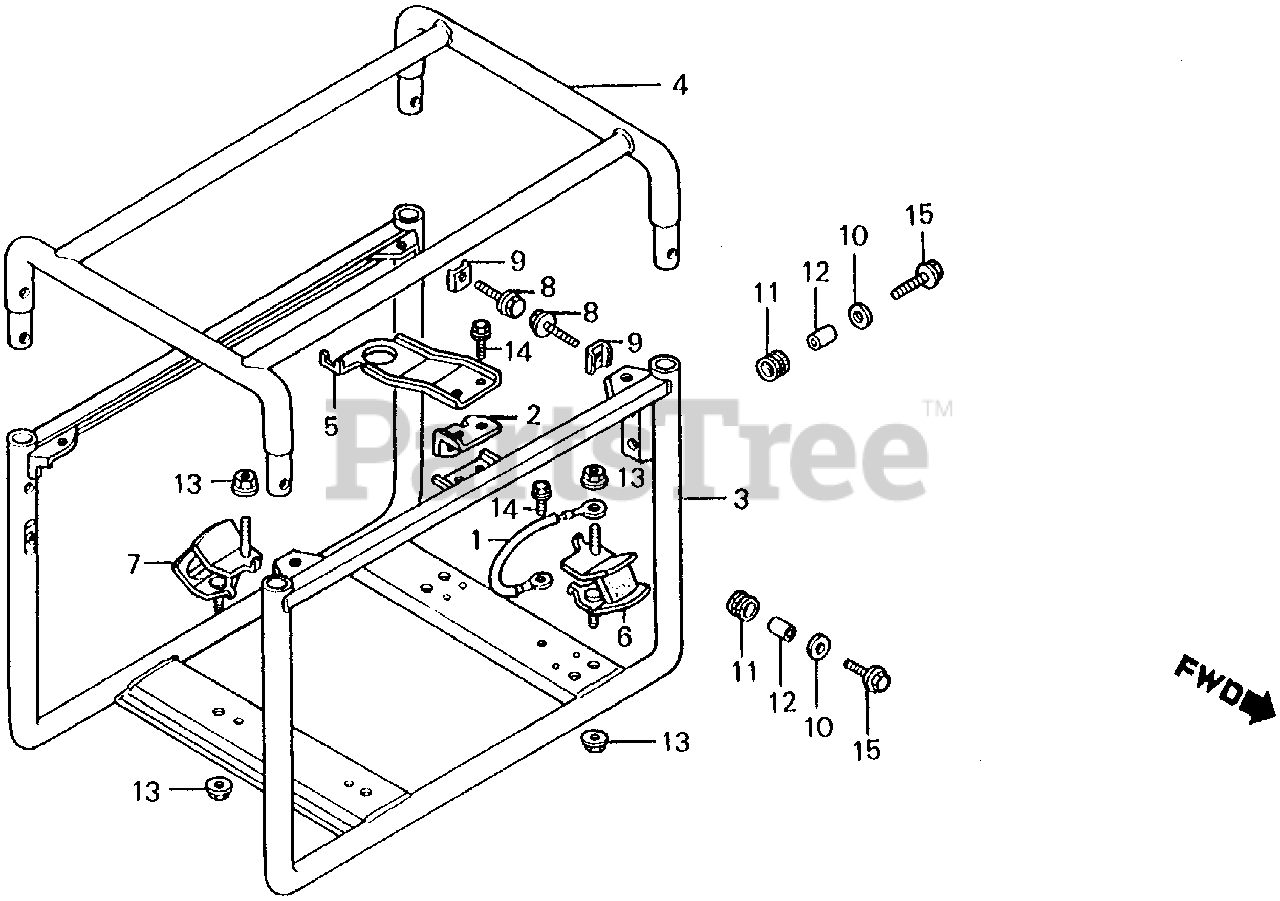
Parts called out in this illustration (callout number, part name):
1	CABLE, GROUND
2	BRACKET, CONTROL BOX MOUNTING
3	FRAME (LOWER)
4	FRAME (UPPER)
5	STAY, BUMP STOP
6	RUBBER, FR. (LOWER)
7	RUBBER, RR. (LOWER)
8	BOLT, FLANGE (8X20)
9	WASHER, FRAME JOINT
10	WASHER, FLAT (20MM)
11	RUBBER, CONTROL BOX
12	COLLAR, CONTROL BOX
13	NUT, FLANGE (8MM)
14	BOLT, FLANGE (6X10)
15	BOLT, FLANGE (6X18)
